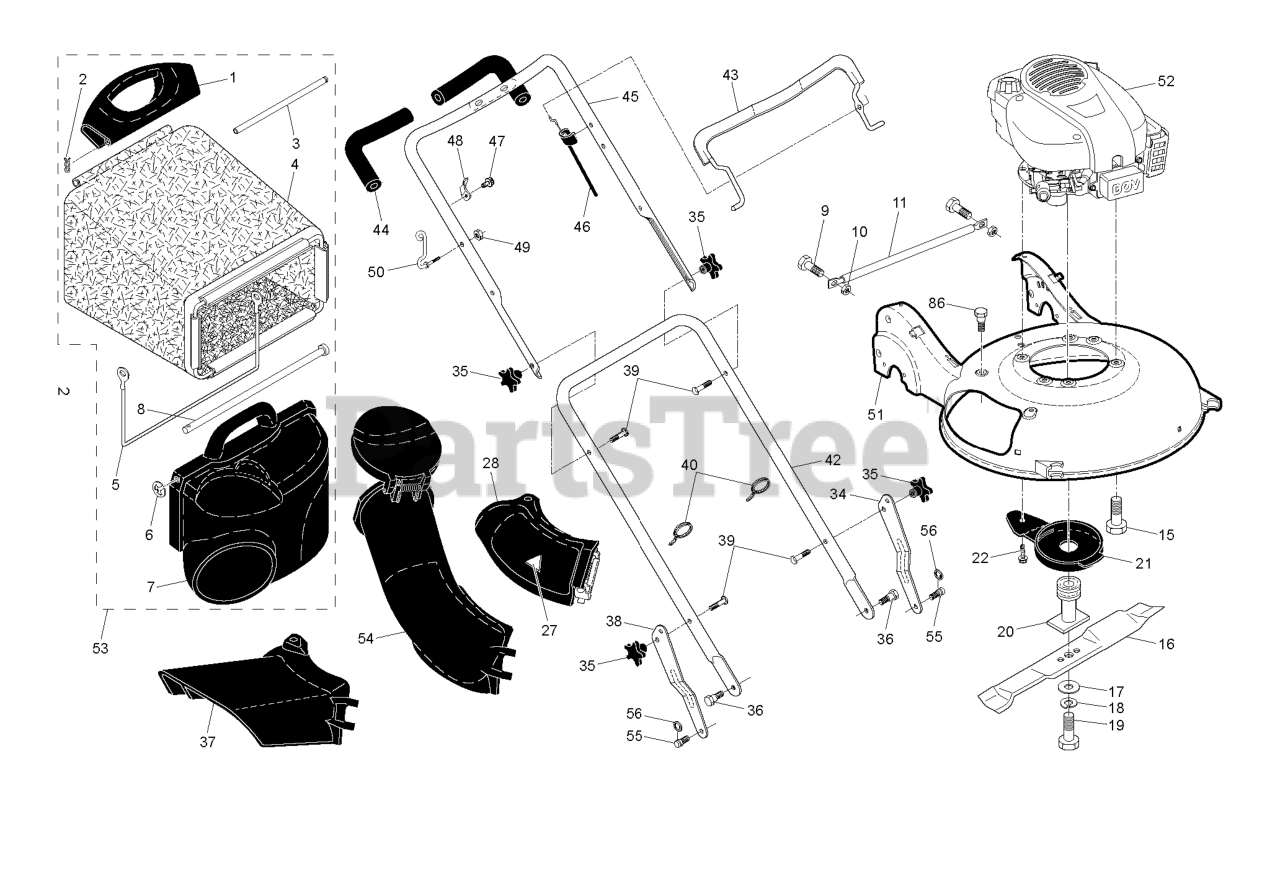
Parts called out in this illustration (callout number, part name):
1	HANDLE.GRASSBAG.REAR.H-GRAY
2	COTTER PIN (3 2)(2 2MC)
3	ROD.REAR.HANDLE.YELLOW
5	FRAME, GRASSBAG
7	DOOR, GRASSBAG
8	ROD, PIVOT
10	LOCKNUT.NYLOC.1/4-20
11	TUBE, REAR SKIRT
15	BOLT 3/8-16X1-1/8
16	Blade, 21"
17	WASHER,HARDEN
18	LOCKWASHER
19	BOLT.HD.HEAD.3/8-24X2.50 (2 2)
20	ADAPTER.BLADE
21	DEBRIS SHEILD
22	SCREW 1/4X20
27	DECAL.INTERNATIONL.CUTFINGER
34	ADJUSTMENT BRACKET, LOWER LH
35	KNOB.HANDLE.PLASTIC.STAR.BLACK
36	SCREW.5/16X.680.TRIM.H
37	GUARD.CLIP.ON.21.HV.GRAY
38	BRACKET.ADJ.LOWER.HDL.RT.GREY
39	BOLT, HANDLE 5/16-18X1.75
40	TIE GUIDE
42	HANDLE.LOWER.GREY
43	BAIL.CONTROL.MZR.BS.ORANGE
44	GRIP.HANDLE.FOAM.WIDE.(1 SIDE)
45	HANDLE.ASM.UPPER.W/GRIP
46	CABLE.MZR.SNAP-IN
48	BRACKET.UPSTOP.RT
49	NUT
50	GUIDE.ROPE.WALK.MOWER
53	Grassbag Assembly, Complete
55	STUD.SHOULDER.T45.BZP
56	E-RING 7/16 RE
